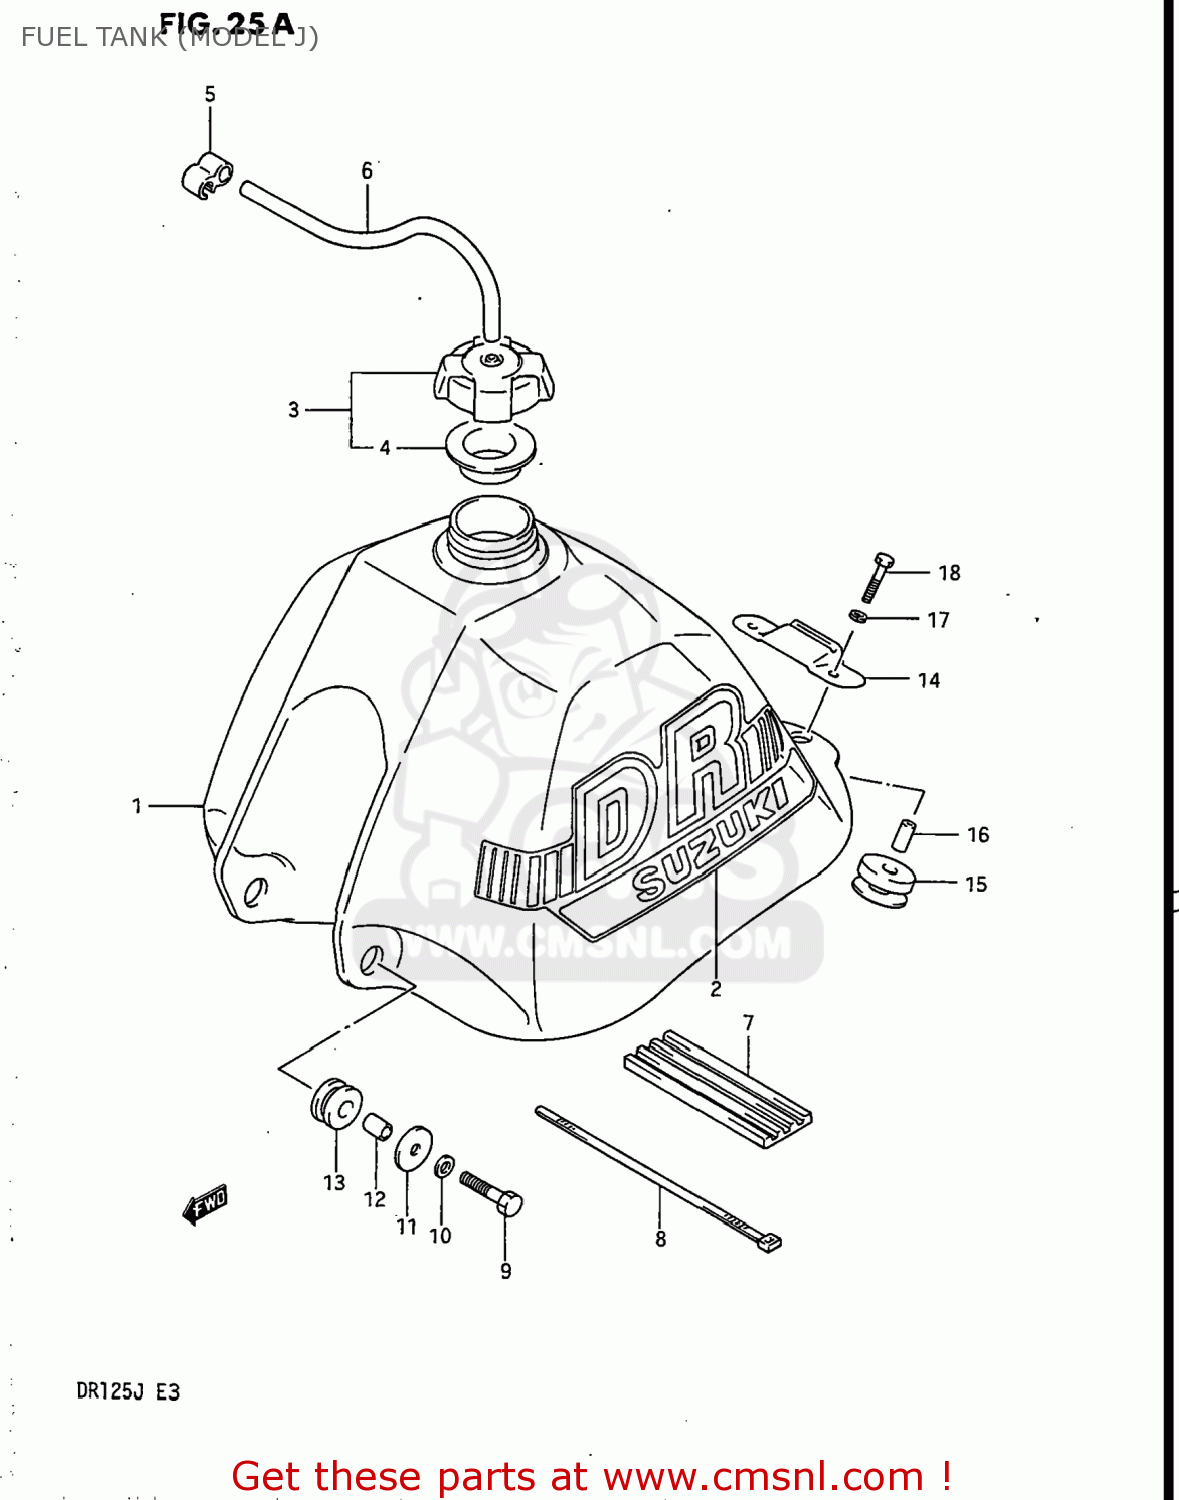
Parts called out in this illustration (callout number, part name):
1	TANK ASSEMBLY,FUEL
2	TAPE SET,FUEL TANK STRIPE
3	CAP SET,FUEL TANK
4	GASKET,FUEL TANK CAP (NAS)
5	CLAMP,FUEL TANK BREATHER HOSE
6	HOSE
7	CUSHION,FUEL TANK UPR FR
8	CLAMP
9	BOLT
10	LOCK WASHER
11	WASHER (8.5X29X1.6)
12	SPACER (8.8X12X13.5)
13	CUSHION
14	PLATE,SEAT FR HOOK
15	CUSHION
16	SPACER
17	WASHER,LOCK
18	BOLT
